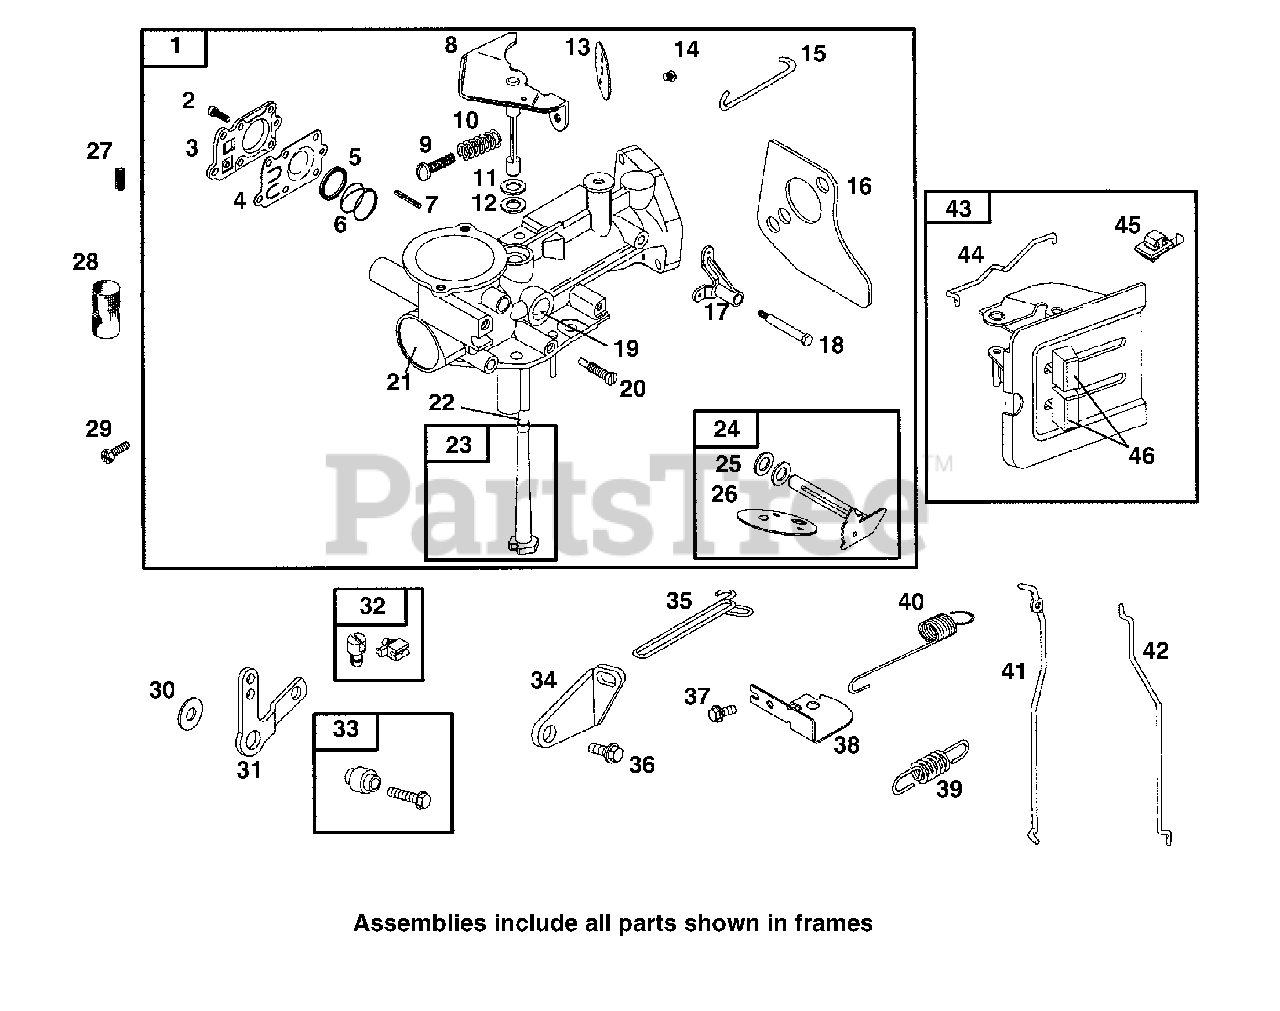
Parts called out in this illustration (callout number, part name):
1	Carburetor
2	Slotted Screw
3	Diaphragm Cover
4	Pump Diaphragm
5	Spring Cap
6	Pump Diaphragm Spring
7	Locating Pin
8	Throttle Shaft
9	Slotted Screw
10	Friction Spring
11	Throttle Shaft Seal
12	Throttle Shaft Seal
13	Throttle Valve
14	Choke/Throttle Screw
15	Throttle Link
16	Intake Gasket
17	Bell Crank
18	Shoulder Screw
19	Welch Plug
21	Welch Plug
23	Pick-Up Tube
24	Choke Shaft Kit
25	Choke Shaft Washer
26	Spacer Washer
27	Detent Spring
28	Carburetor Screen
29	Torx Hex Screw
30	Flat Washer
31	Bell Crank
32	Link Retainer
33	Bell Crank Collar
34	Link Bracket
35	Bell Crank Link
36	Hex Screw
37	Hex Screw
38	Spring Anchor
39	Governor Spring
40	Governor Idler Spring
41	Governor Control Rod
42	Mechanical Governor Link
43	Control Bracket
44	Choke Link
45	Stop Switch
46	Control Knob
